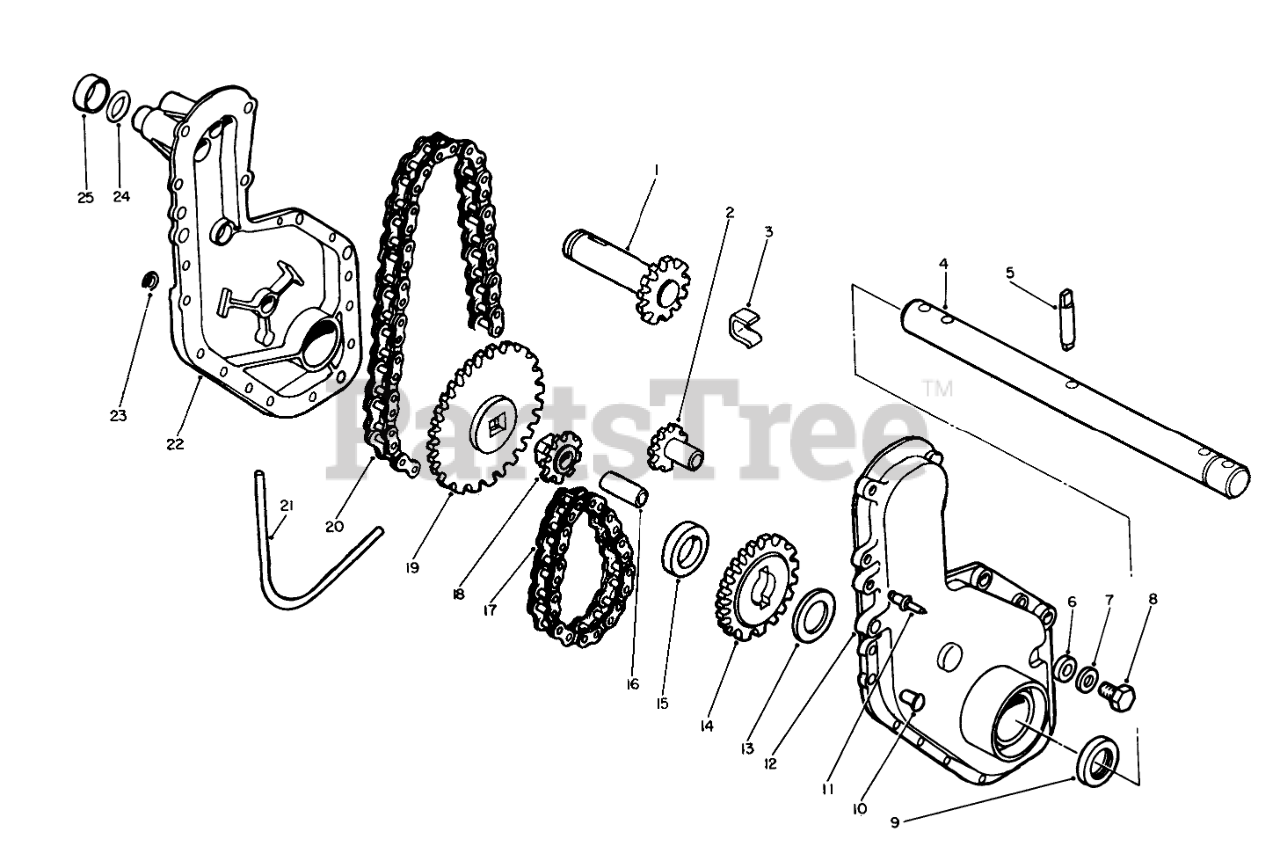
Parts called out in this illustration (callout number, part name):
1	Input Shaft
2	Idler Sprocket-9 Tooth
3	"U" Clip
4	Axle
5	Drive Pin
6	Nylon Washer
7	WASHER-PLAIN
8	SCREW-HH
9	Seal
10	Rivet
11	Pop River
12	Chain Case R.H.
13	Washer
14	Sprocket-27 Tooth
15	Washer
16	Shaft-Sprocket
17	#35 Roller Chain
18	Sprocket-10 Tooth
19	Sprocket
20	Chain-Upper
21	Gasket
22	Chain Case-L.H. w/Bearing
23	WASHER-PLAIN
24	O-Ring
25	Seal Cup
